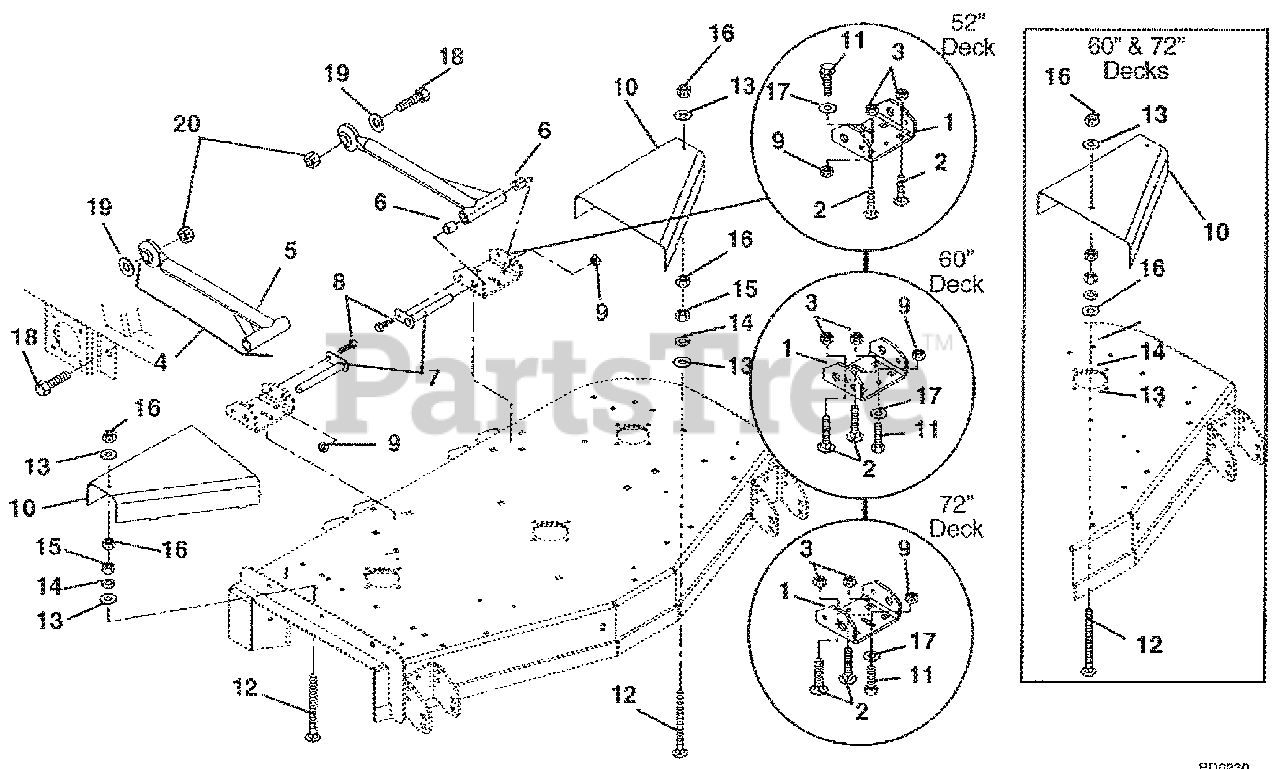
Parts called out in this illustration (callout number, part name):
1	Bracket, Mower Mounting (Rear)
2	Bolt, Round Head Square Neck .50-13 x 1.00 Grade 5
3	Nut, Locking Center Jam .50-13
4	Assembly, Mower Mounting Arm (Includes Items 5 and 6)
5	Weldment, Mower Mounting Arm
6	Bearing .75 x .875 x 1.00
7	Weldment, Mower mounting Pin
8	Bolt, Hex .38-16 x .75 Grade5
9	Nut, Locking Top Flange .38-16
10	Guard, Pulley Right Hand (066, 071)
11	Bolt, Hex .38-16 x 1.00 Grade 5
12	Bolt, Round Head Square Neck .31-18 x 3.50 Grade 5
13	Washer, Flat Steel .344 x .688 x .065
14	Washer, Locking .31 x .078
15	Nut, Hex .31-18
16	Nut, Locking Center .31-18
17	Washer, Flat Steel .406 x .812 x .065
18	Bolt, Hex .875-9 x 2.75 Grade 5
19	Washer, Flat Steel .875 x 1.50 x .120
20	Nut, Locking Center .875-9
